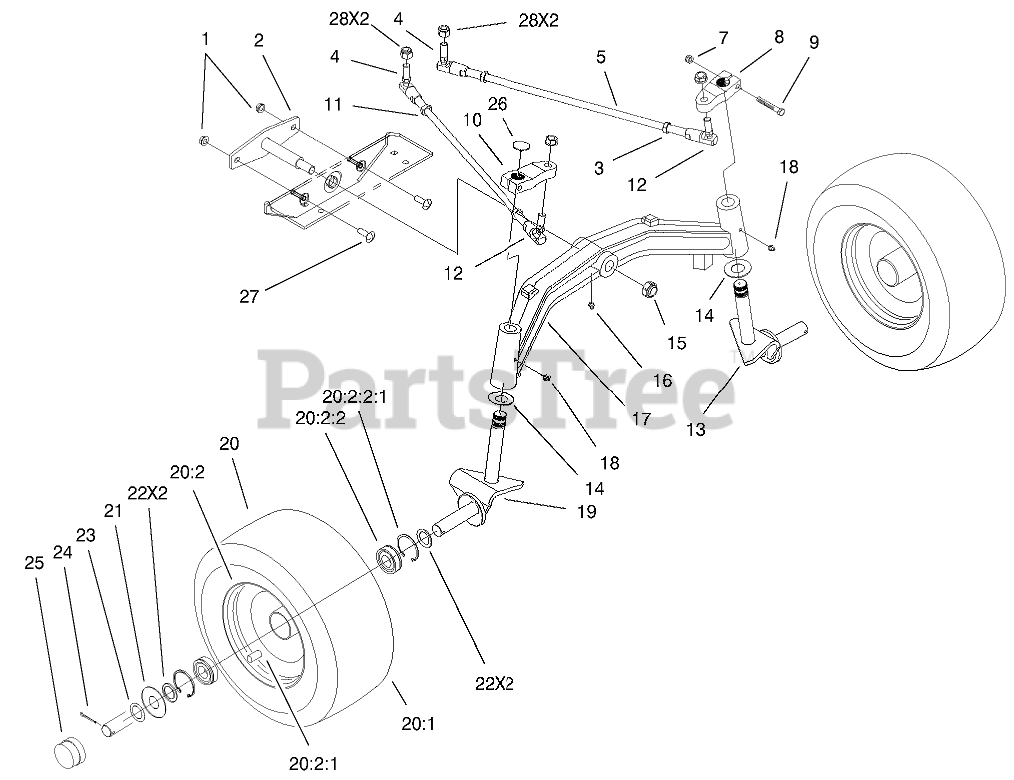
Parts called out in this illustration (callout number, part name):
1	NUT-LOCK, NI
2	Pin-Pivot
3	NUT-JAM
4	BALLJOINT-THREAD, LH
5	ROD-TIE
7	NUT-LOCK, NI
8	ARM-STEERING, LH
9	SCREW-HH
10	ARM-STEERING, RH
11	NUT-HJ (LH THREAD)
12	BALLJOINT-THREAD. RH
13	SPINDLE-LH
14	WASHER-THRUST
15	NUT-LOCK
16	FITTING-GREASE
17	AXLE-FRONT
18	FITTING-GREASE
19	SPINDLE-RH
20	Wheel & Tire ASM
20:2	RIM ASM
20:2:1	VALVE
20:2:2	BEARING
20:2:2:1	Ring-Snap
21	WASHER-WHEEL
22	Washer
23	WASHER
24	PIN-COTTER
25	CAP-DUST
26	CAP - SPINDLE
27	BOLT-CARR
28	NUT-LOCK
